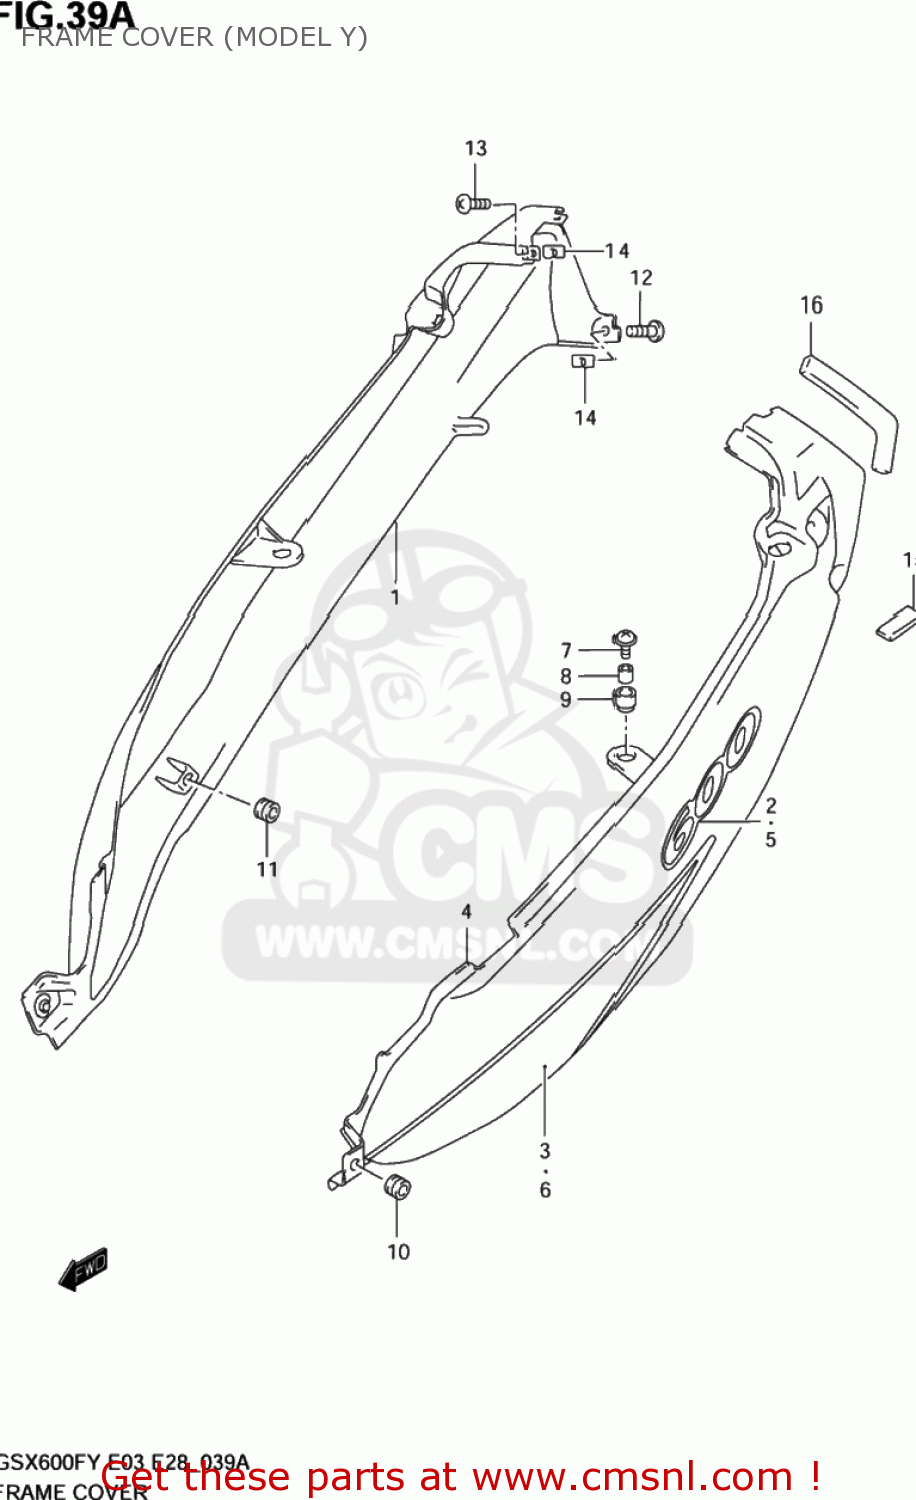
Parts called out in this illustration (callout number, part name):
1	COVER,FRAME,R(RED)
2	EMBLEM,FRAME COVER
3	TAPE,FRAME COVER,R
4	COVER,FRAME,L(RED)
5	EMBLEM,FRAME COVER
6	TAPE,FRAME COVER,L
7	SCREW(6X20)
8	SPACER(6.5X10X9.4)
9	CUSHION
10	CUSHION
11	CUSHION
12	SCREW
13	SCREW
14	NUT
15	CUSHION
16	CUSHION,FRAME COVER
